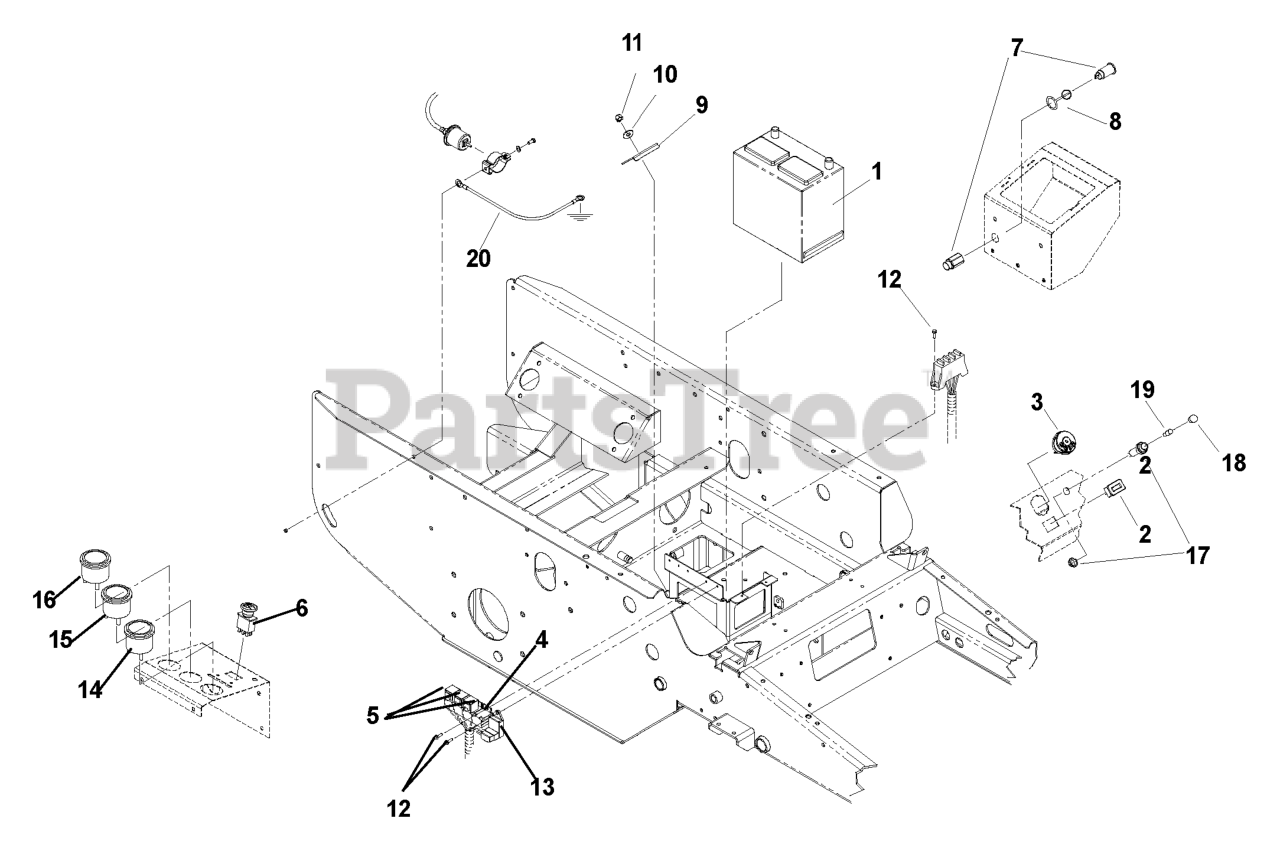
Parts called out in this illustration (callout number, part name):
2	DIGITAL HOUR METER
3	RP IGNITION SWITCH
6	RP.SWITCH, BLADE
7	POWER SOURCING HSG
8	POWER SOURCE CAP
10	WASHER 5/16 FLAT
11	NUT 5/16 NYLOC
12	SCR #10-12X3/4 HEX WAS HD ZD
13	TIMER/GLOW PLUG
14	TEMP GAUGE DATCON #100182
15	GAUGE, AMPMETER DATCON 100160
16	GAUGE, OIL PRES DATCON 100172
17	LAMP SPROCKET
